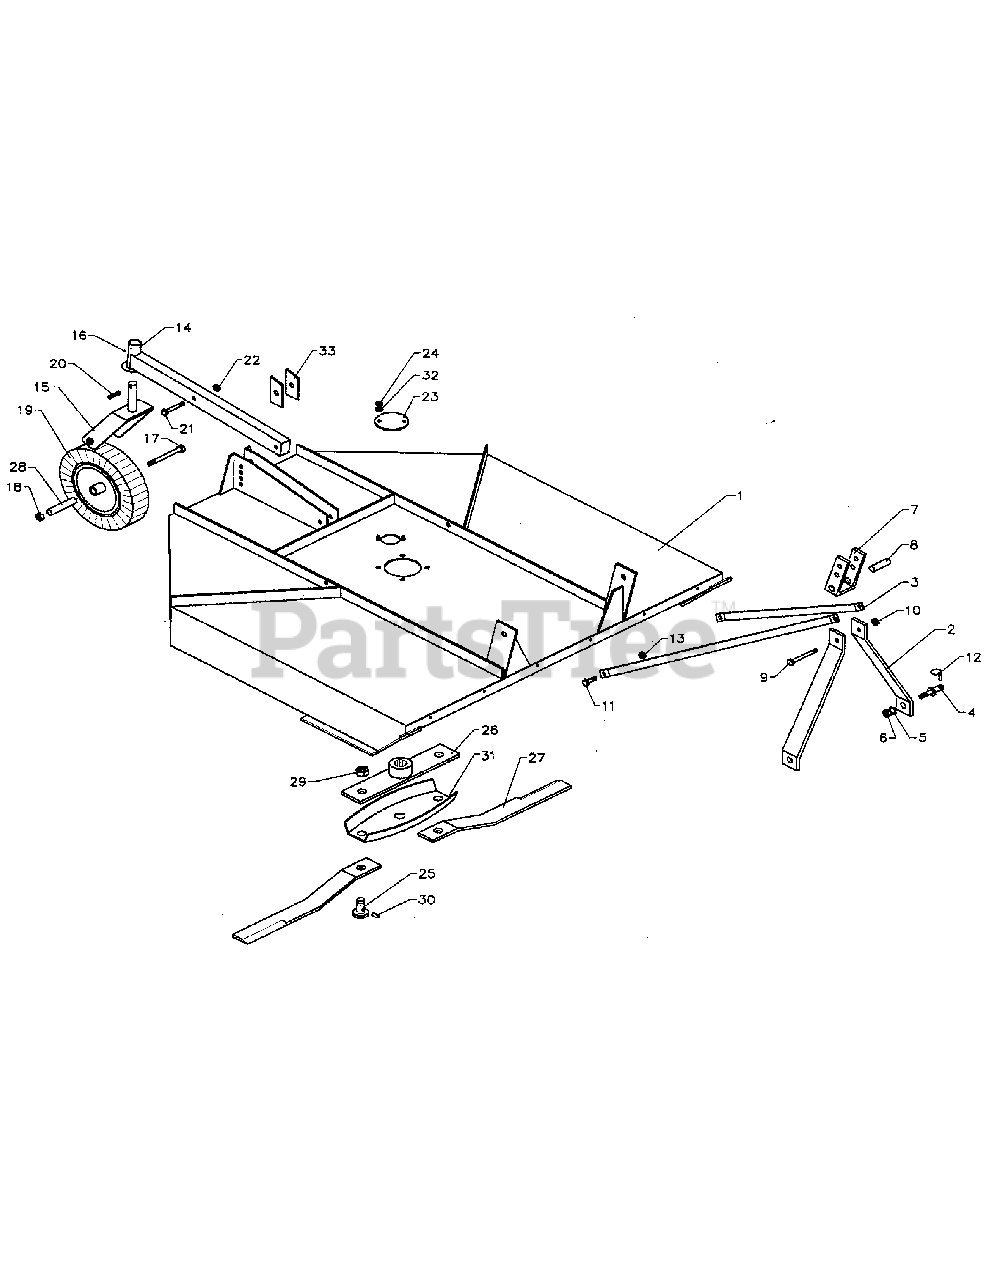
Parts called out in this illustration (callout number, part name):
1	ROUND BACK FRAME COMPLETE
2	VERTICAL SUPPORT
3	HORIZONTAL SUPPORT 60"
4	HITCH PINS
5	HEX NUT 5/8"
6	LOCKWASHER 5/8"
7	TOP HITCH PLATE
8	INNER SPACER
9	BOLT 5/8" X 7"
10	STOVER NUT 5/8"
11	BOLT 14 X 40
12	LYNCH PIN
13	STOVER NUT 14MM
15	WHEEL YOKE
16	GREASE FITTING
17	BOLT 3/4" X 7"
18	JAM NUT 3/4"
19	LAMINATED TIRE
20	ROLL PIN 10 X 40
21	BOLT 16 X 90
22	STOVER NUT 16MM
23	ACCESS PLATE
24	NYLOCK NUT 10MM
26	BLADE ROTOR W/BUSHING
28	WHEEL SPACER
29	NUT 27MM
30	BLADE STOP PIN
31	STUMP JUMPER (60", 72" ONLY)
32	FLAT WASHER 10MM
33	SPACERS
